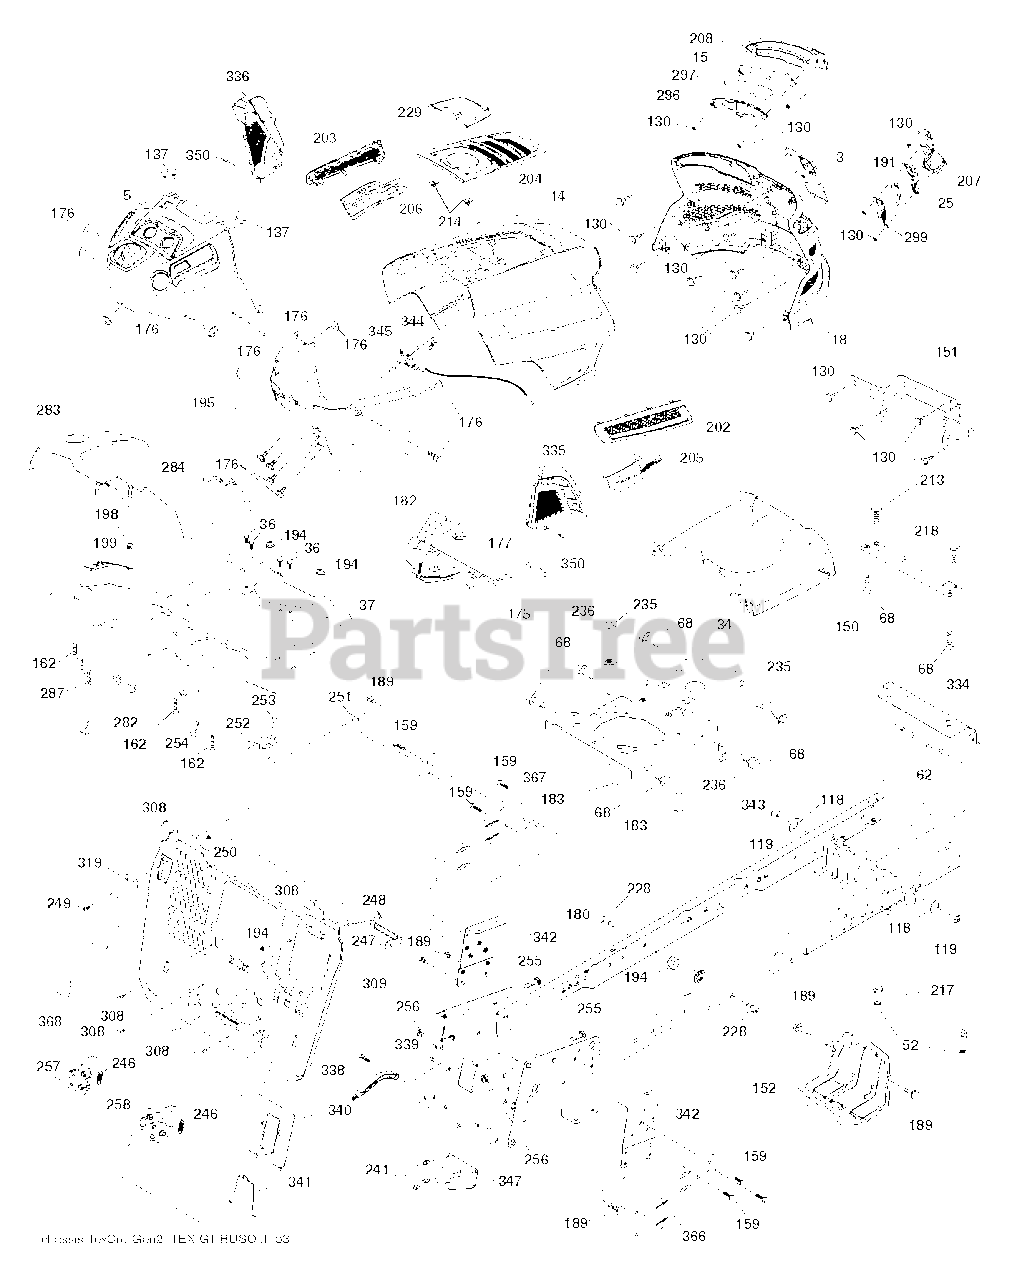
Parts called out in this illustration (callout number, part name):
3	APPLIQUE.SUBASM.GT.HUSQ.II
5	DASH.UPP.GT2.DUAL.RD.PT
14	HOOD.ASM.HUSQVARNA.GT.TEX.ORAN
15	LED LIGHT.LH
18	GRILLE SUBASM.GT.II.LOW.HDLGHT
25	LENS.RH
34	PLATE.ENGINE.10GA.CRD.GENII
36	SCREW 5/16"
37	FENDER.TEX.SRD.CRD.BASE
52	LOCKNUT
62	BOLT D
68	SCREW LT
118	WASHER
130	SCREW.#10 X 0.750.BOS
137	BUMPER DASH
150	AIR.DUCT.GTV.BLACK
151	BRACKET.PIVOT.HOOD.GT.HUSQ.II
152	SHIELD.BROWNING.PNT.GT.V2
159	SCREW, 3/8-16X3/4
162	SCREW.HI-LO.CONSOLE
175	PLATE.CROSSMEMBER.HUSQ
176	SCREW.#10-24X5/8.RN.QU
177	BUSHING STEERING
180	WELDMENT.CHASSIS.TEX.CRD.GEN.2
182	DASH DASH LOWER
183	BOLT.5/16-18X1-1/4 FULL THD
189	SCREW
191	INSERT INFLECT.RH
194	NUT LOCK HEX FLANGE 5/16-18
195	PLUG.HOLE.DASH.LOWER.12V.BLK
198	INDICATOR.DECK.LIFT.RED
199	PLATE DECK LIFT
202	VENT.SIDE.RH.GT.HUSQ.II.
203	VENT.SIDE.LH.GT.HUSQ.II.498
204	VENT.TOP.EXTERNAL.FILL.GT2.GRE
205	SIDE.TRIM.RH.GT.HUSQ.II
206	SIDE.TRIM.LH.GT.HUSQ.II.GRAY
207	BEZEL GT2 LED RH W/ LOWER.ATT
208	BEZEL GT2 LED LH W/ LOWER ATT
213	BOLT
214	CLIP.RETAINER.TINNER.
217	ROD.PIVOT.HOOD
218	X-PIECE.HOOD.STOP.NON/
228	STUD.FASTNER.W/ANTI-ROTATE
229	LID.EXT.FILL.GT.HUSQ2.BLACK
235	SPACER FENDER
236	NUT.CENTERLOCK.5/16-
241	SCREW 5/16-18X1
246	SPRING.TCRD.GEN2.5.BAGGER.EXT
247	STRAP.BATTERY.TCRD.GE
248	BOLT
249	SCREW.BUTTONHD.10-24X1/2.(2 2)
250	NUT 10-24 NYLOC
251	BRACKET.PNT.LH.SUPP.B
252	BRACKET.PNT.RH.SUPP.B
253	BOLT
254	NUT T
255	BOLT CROSS DRILLED CUP HEAD SQ
256	Hex Nut, 3/8-16
257	LATCH.ASM.BGR.LH.GEN2
258	LATCH.ASM.BGR.RH.GEN2
282	CLIP.RETAINER.CONSOLE.LT.HUSQ
283	CONSOLE.DECKLIFT.CRDII.498
284	CONSOLE.PEDAL.HYDRO
287	SCREW 1/4X20
296	LED LIGHT.LH
297	INSERT REFECT LH
299	LED LIGHT.RH
308	BOLT, 5/16-18 X 1 3/4
309	BACKPLATE.TEXCRD2.5.B
319	LEVER.PRSNC.BGR.TEX.C
334	BRACKET.ENGINE
335	COVER.LOWER.DASH.RH.BLACK
336	COVER-LH.LOWER.DASH.GT2.BLACK
338	BOLT BOLT SHOULDER
339	LEVER LEVER BAGGER
340	BATTERY.DOOR.TCRD.GEN
341	LATCH.BATTERY.DOOR.TC
342	SUPPORT.PNT.FENDER.CRD.TEX
343	CLIP CLIP
344	CONTROL.EZ.MULCH.TEX/CRD
345	RP KNOB.OVAL.TAPERED.3/8-16BLK
347	HITCH HITCH TOW TEX CRD GEN 2
350	CLIP.X-MAS.TREE
366	BRACKET.RH.FRONT.BAGGER.BLACK
367	BRACKET.LH.FRONT.BAGGER.BLACK
368	FULL.LEVER.BAGGER.TEX.CRD
